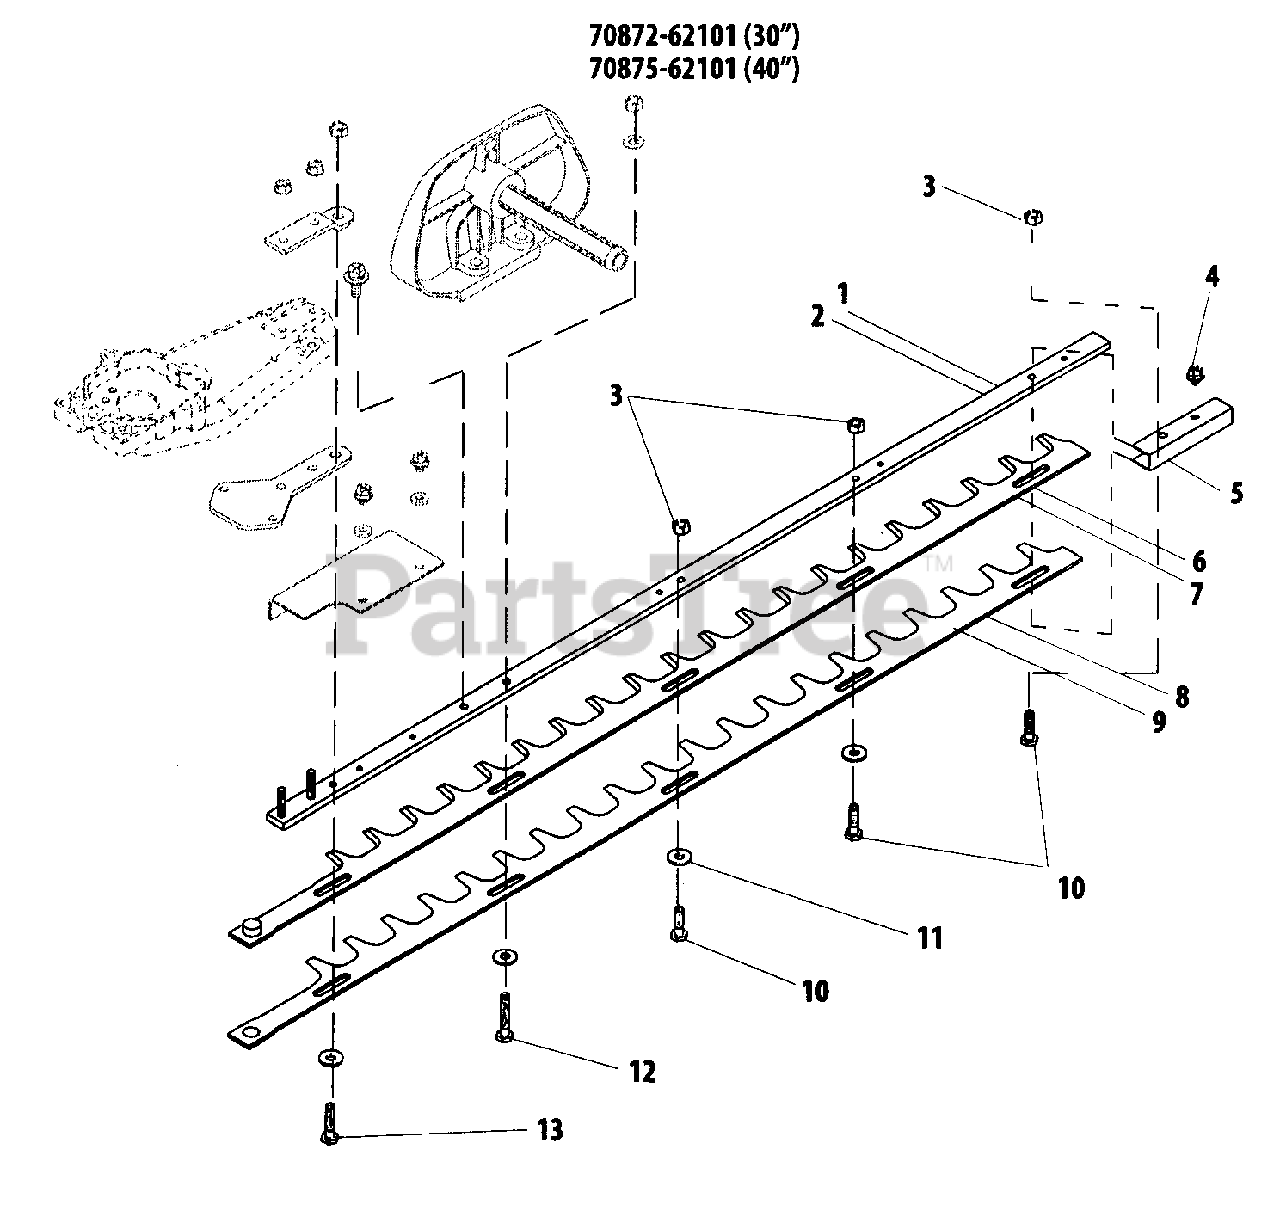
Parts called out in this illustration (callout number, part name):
1	SUPPORT, BLADE - 30" (76cm)
2	SUPPORT, BLADE - 40" (101cm)
3	NUT - 6
4	BOLT - 5X8
5	PLATE, GUIDE
6	BLADE - 30" (76mm) -- UPPER
7	BLADE - 40" (101cm) -- UPPER
8	BLADE - 30" (76mm) -- LOWER
9	BLADE - 40" (101cm) -- LOWER
10	BOLT - 6X20
11	WASHER - 6
12	BOLT - 6X32
13	BOLT
70872-62101	BLADE KIT - 30" (76cm)
70875-62101	BLADE KIT - 40" (102cm)
